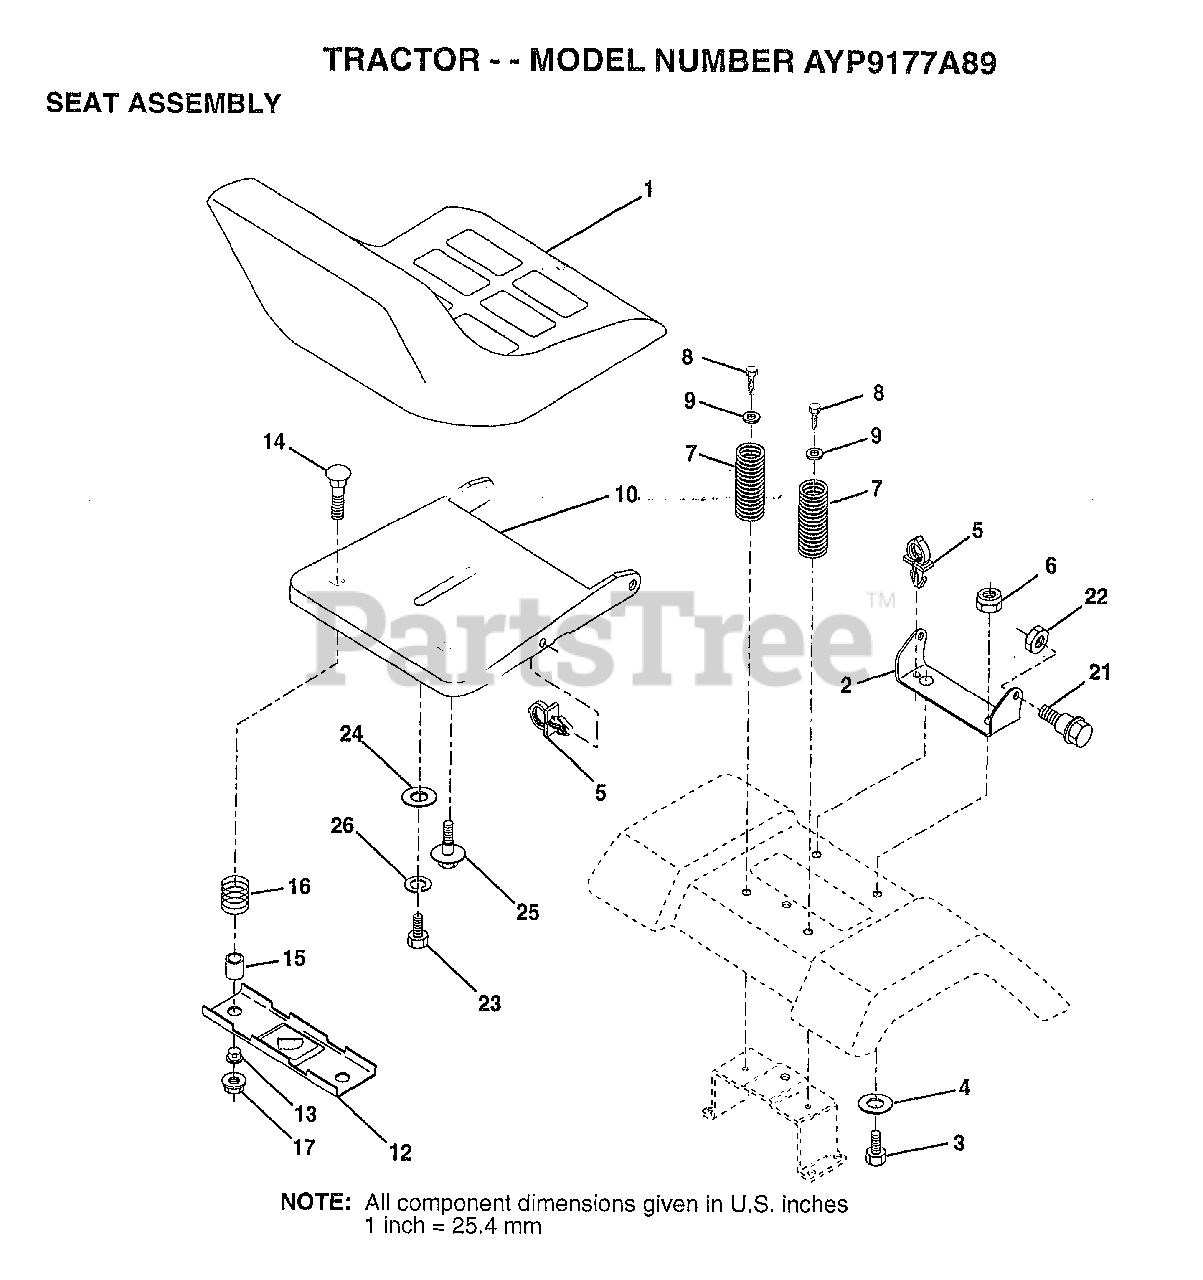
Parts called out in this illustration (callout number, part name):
1	SEAT.2400/1416.BK
2	BRACKET PVT SEAT
3	BOLT
4	WASHER PM
5	CLIP.PUSH-IN.HING
6	NUT
7	SPRING COMPRESSIO
8	SCREW GTV
9	WASHER
10	PAN-SEAT
12	BRKT SWITCH
13	BUSHING
14	BOLT-RD HD SQ NK
15	SPLIT SPACER
16	SPRING
21	"BOLT,SHOULDER"
22	NUT
23	BOLT
24	WASHER
25	"BOLT,SHOULDER"
26	LOCKWASHER
